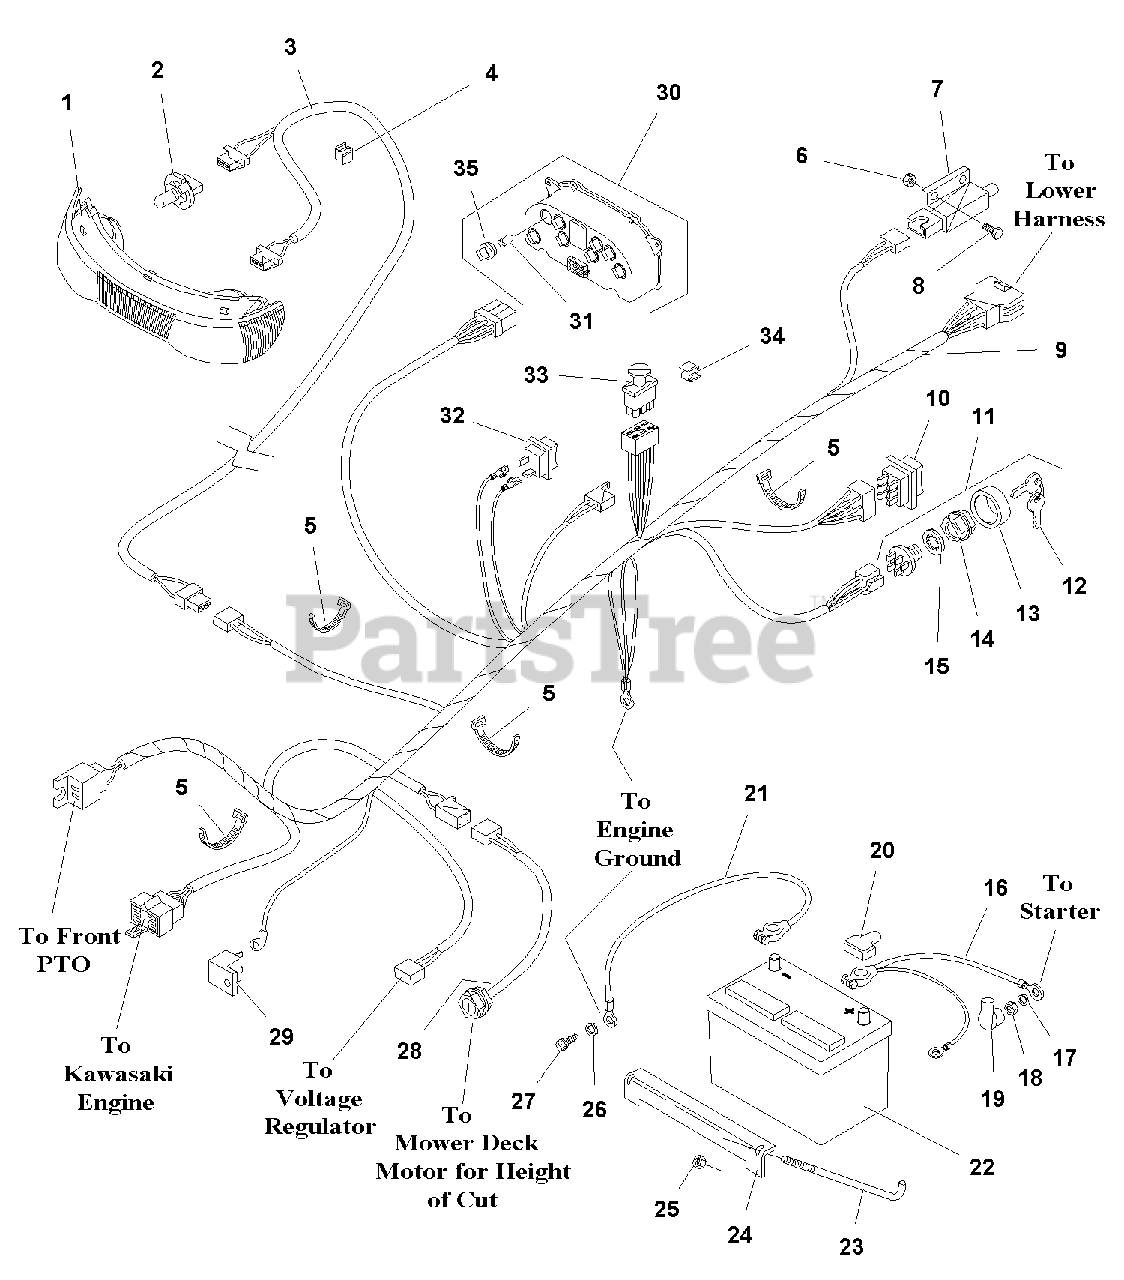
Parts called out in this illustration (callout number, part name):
1	BEZEL, Headlight
2	BULB, Headlight, Halogen
3	HARNESS, Headlight
6	NUT, KEPS Lock, #10-24
7	SWITCH, Interlock (NO/NC)
8	CAPSCREW, #10-24 x 5/8
9	HARNESS, Main
10	SWITCH, Mower Height Adjust
11	ASSEMBLY, Switch & Key (Includes Ref. Nos. 12 -15)
12	KEYS (Set of 2)
13	COVER, Key Switch
14	NUT, Hex Flange, 5/8
15	WASHER, Internal Tooth, 5/8
16	CABLE, Battery to Starter, Kohler Engines
17	LOCKWASHER, 5/16
18	NUT, Hex Jam, 5/16-24, Kohler Engines
19	COVER, Starter Terminal
20	COVER, Positive Battery Terminal
21	CABLE, Battery to Ground
22	BATTERY (500 CCA)
23	ROD, Battery Hold Down
24	BRACKET, Battery
25	NUT, Hex, Nylon Lock, 1/4-20
26	LOCKWASHER, 7/16
27	CAPSCREW, 7/16-14x 5/8
28	HARNESS, Power Outlet
29	BREAKER, Circuit
30	PANEL, Instrument (Includes Bulbs & Bulb Holders)
31	BULB, Instrument Panel
32	SWITCH, Headlights
33	SWITCH, Front P.T.O.
35	HOLDER, Bulb
